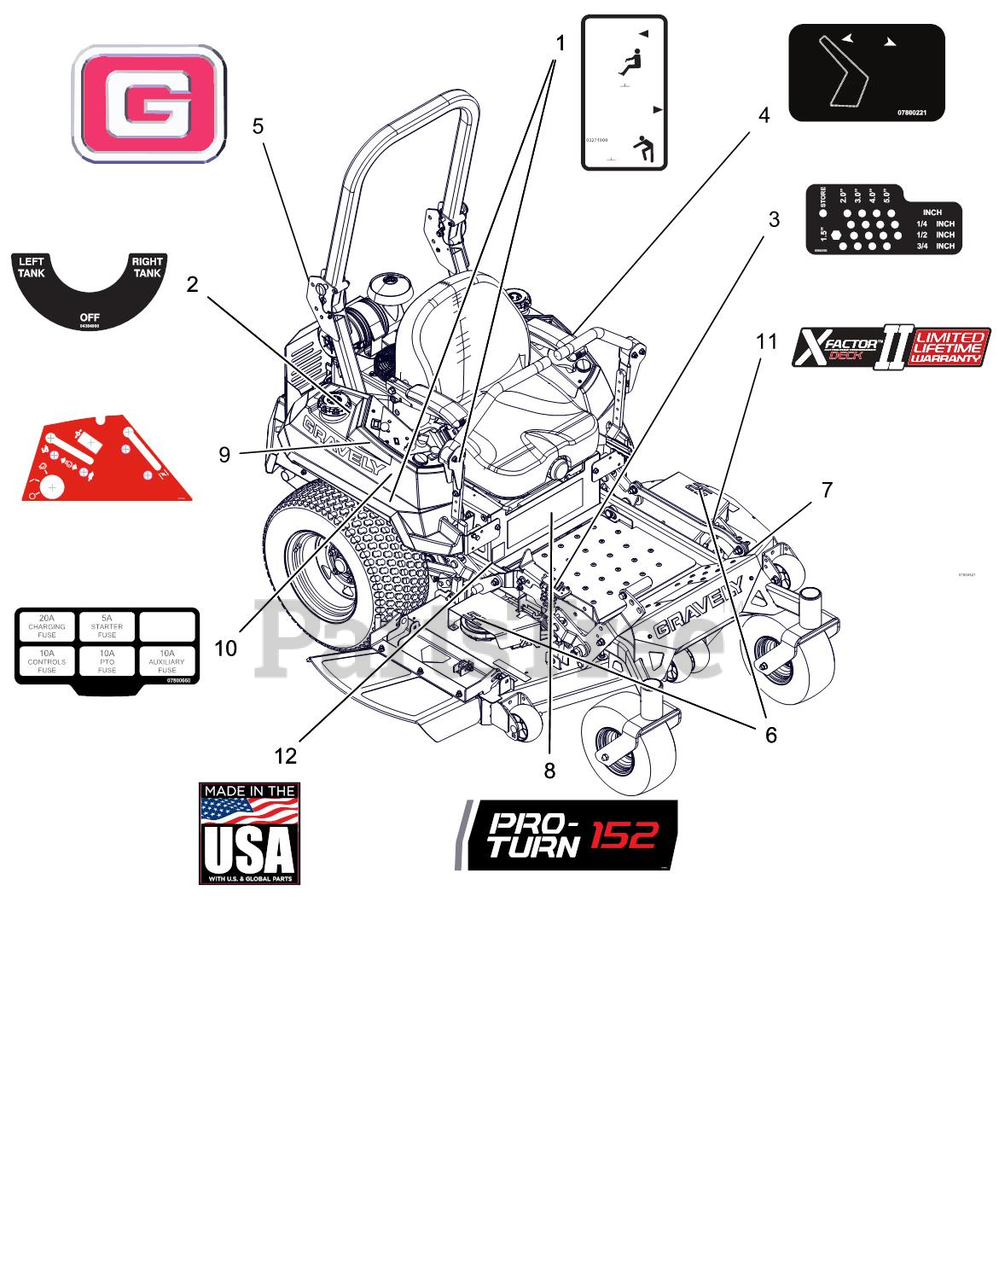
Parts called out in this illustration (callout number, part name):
1	DECAL, TRANSMISSION DISCONNECT
2	DECAL, FUEL VALVE
3	DECAL, HEIGHT OF CUT
4	DECAL - SEAT RELEASE
5	DECAL, GRAVELY BRAND
6	DECAL, 52"
7	DCL,BELT ROUTE-RH V-SIDE IDLER
8	DECAL, PRO-TURN 152
9	DECAL, NON-EFI CONTROL PANEL
10	DECAL, FUSE BLOCK
11	DECAL, X-FACTOR DECK
12	DECAL, MADE IN USA
